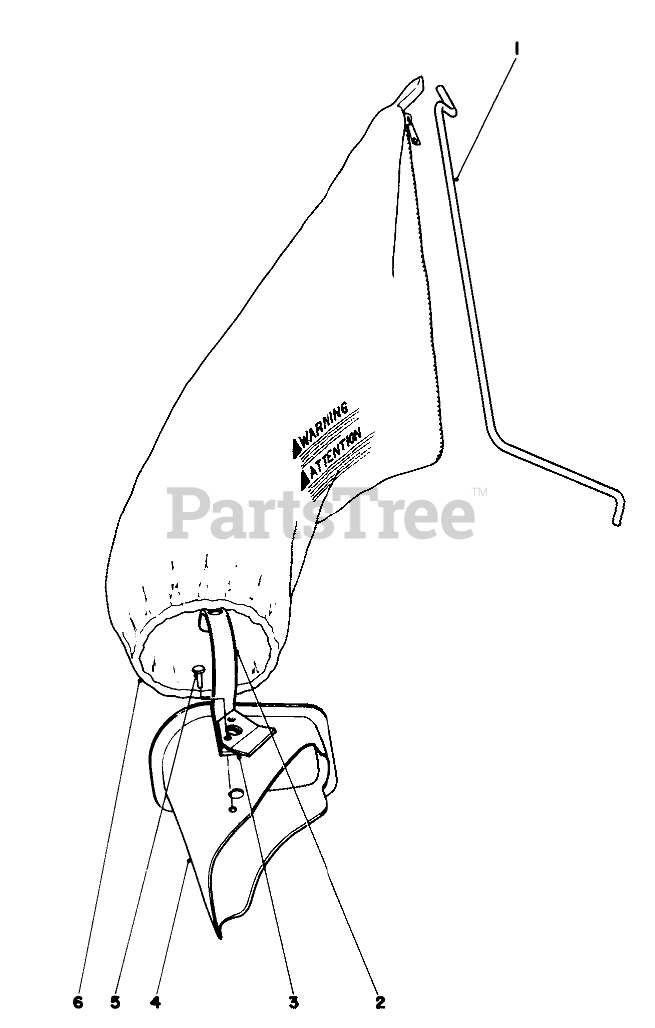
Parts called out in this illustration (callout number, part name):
1	BAG HANGER ROD
2	BAG CHUTE HANDLE
3	Stop Deflector
4	Grass Chute (Incl. Ref. #2 & 4-5)
5	Rivet Semi Tubular
6	Grass Bag
